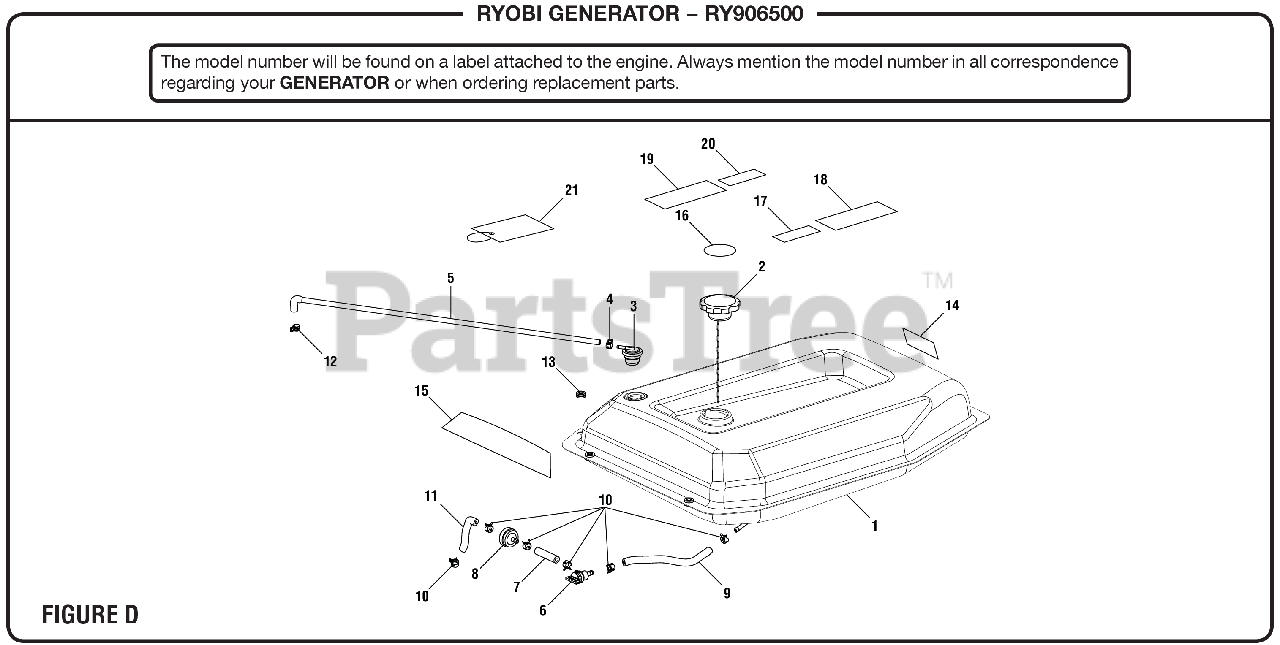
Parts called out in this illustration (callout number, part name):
1	Fuel Tank
2	Fuel Cap Assembly
3	Fuel Tank Vent Valve (PS905055SA)
4	Fuel Line Clamp (10.3 mm)
5	Vapor Hose (590 mm and 30 mm)
6	Fuel Shut Off Valve
7	Fuel Hose (55 mm)
8	Fuel Filter Inline (1/4 in.)
9	Fuel Hose (175 mm)
10	Fuel Line Clamp (1/2 in.).
11	Fuel Hose (185 mm)
12	Fuel Line Clamp (3/8 in.)
13	Fuel Hose Protector
14	UL Fire Warning Label Spark Arrestor)
15	Logo Label
16	Remove Cap Fuel Stabilizer Label (English)
17	Fuel Stabilizer Label (French/Spanish)
18	CPSC (English) Label
19	Warning Label
20	No E85 Label
21	Warning Hangtag
